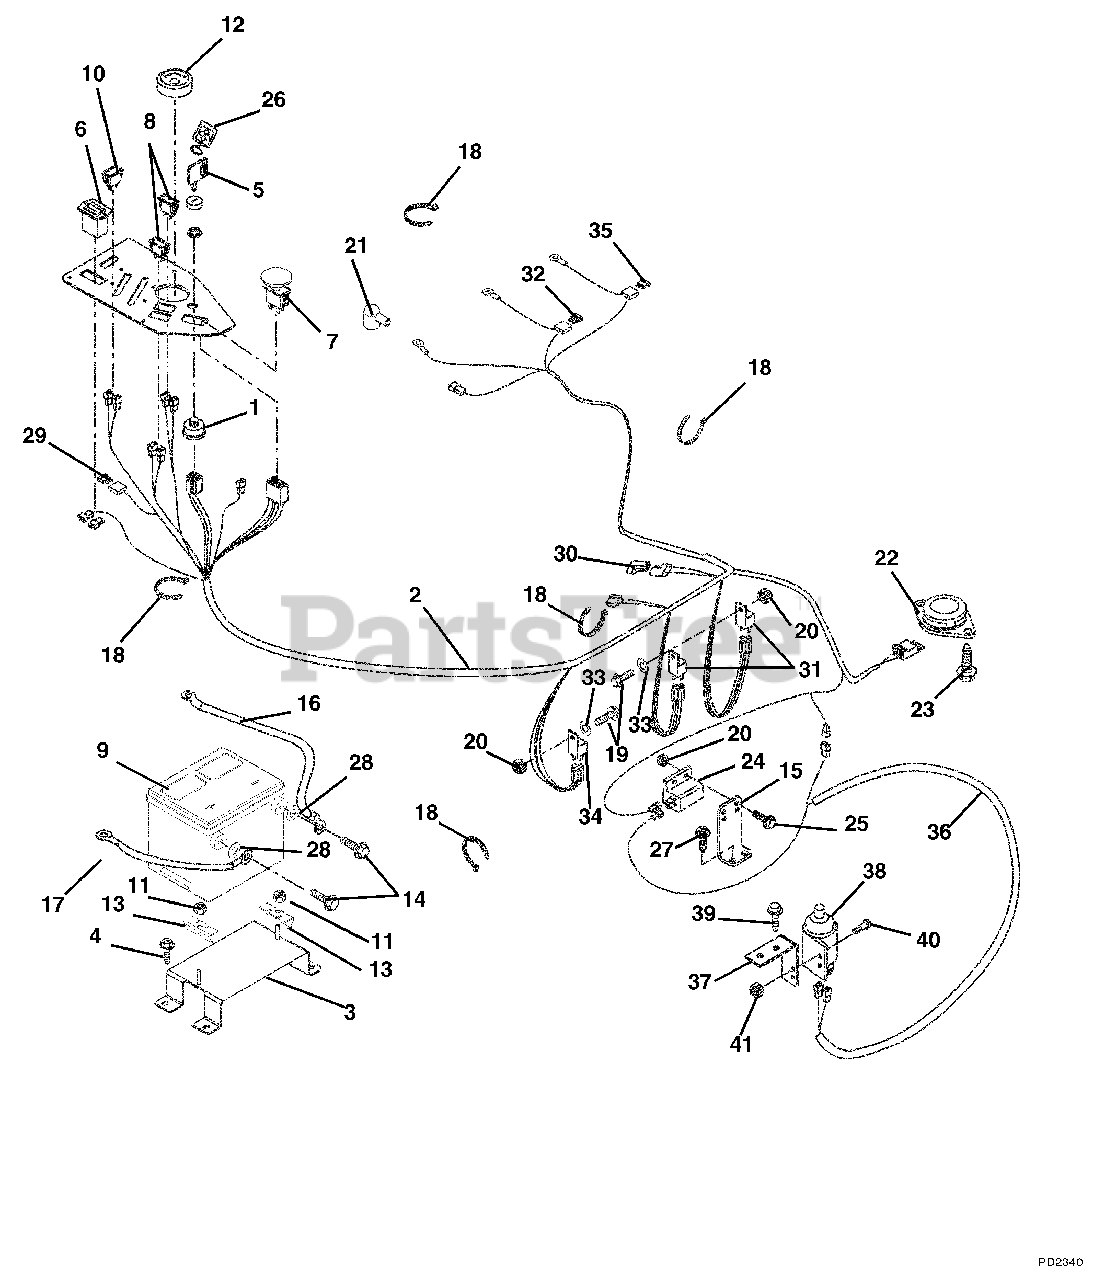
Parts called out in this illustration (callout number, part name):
1	Key Switch (036, 037)
1	Key Switch (038, 039, 309)
2	Harness, Wire (Gas) (036, 037)
2	Harness, Wiring (Diesel) (038, 039, 309)
3	Weldment, Battery Support
4	Screw-Tapping .38-16 x .75 Hex Washer Head
5	Key-with Cap
5	Ignition Key Set
6	Hour Meter
7	Switch-Clutch With Retainer Ring
8	Light-Indicator Kit
9	Battery with Tube
10	Switch, Light
11	Nut-Locking-Nylon .312-18
12	Gauge, Temperature
13	Bracket, Battery Hold-Down
14	Bolt-Hex .25-20 x .75 Grade 5
15	Mount, Safety Switch
16	Positive Cable (036, 037)
16	Positive Cable (038, 039, 309)
17	Ground Cable (036, 037)
17	Cable, Negative Battery (038, 039, 309)
18	Cable Tie
19	Screw-Machine 10-24 x .75 Hex Washer Head (036, 037)
19	Screw-Machine 10-24 x .75 Hex Washer Head (038, 039, 309)
20	Nut-Locking-Nylon 10-24 With Insert (036, 037)
20	Nut-Locking-Nylon 10-24 With Insert (038, 039, 309)
21	Battery Terminal Boot, Red
22	Seat Switch
23	Screw-Tapping 12-24 x .50 Hex Washer Head
24	Switch-Single Pole
25	Screw-Machine 10-24 x .75 Hex Washer Head
26	Key Chain
27	Screw-Tapping .25-20 x .50 Hex Washer Head
28	Washer-Flat-Steel .406 x 1.00 x .188
29	Fuse, 7.5 Amp
30	Molded Diode Plug-Black 1-Amp
31	Relay
32	Fuse, 30 Amp
33	Washer-Flat-Steel .25 x .562 x .049 (038, 039, 309)
35	Fuse, 25 Amp
35	Fuse, 40 Amp
36	Harness, Wire Adapter CE (309)
37	Mount- Switch (309)
38	Switch-Single Pole (N.O.) with Cover (309)
39	Screw-Tapping .31-18 x .50 Hex Washer Head (309)
40	Screw-Machine 10-24 x .75 Hex Washer Head (309)
41	Nut-Locking-Nylon 10-24 with Insert (309)
